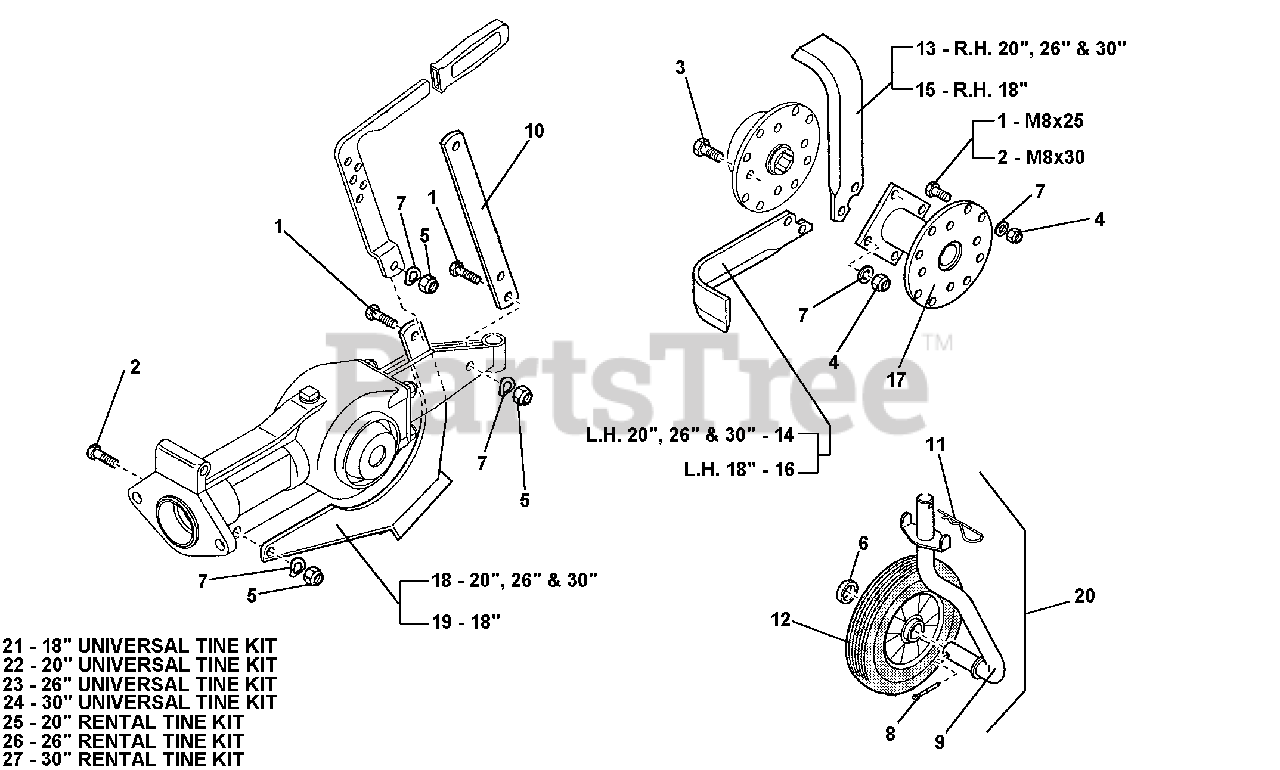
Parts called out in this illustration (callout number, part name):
1	SCREW, M8X25
2	SCREW, M8X30
3	SCREW, M8X35
4	NUT, SELF LOCKING, M8
5	NUT, SELF LOCKING, M8
7	WASHER, LOCK, M8.4
9	WHEEL SUPPORT PIN
12	RUBBER WHEEL
13	TINE, R.H., 20" - 30" TILLER
14	TINE, L.H., 20" - 30" TILLER
15	TINE, R.H., 18" TILLER
16	TINE, L.H., 18" TILLER
17	SPACER KNIVES
18	CERNTAL KNIFE
19	CENTRAL KNIFE
20	TRANSPORT WHEEL ASSEMBLY
21	18" UNIVERSAL TINE KIT
22	20" UNIVERSAL TINE KIT
23	26" UNIVERSAL TINE KIT
24	30" UNIVERSAL TINE KIT
25	20" RENTAL TINE KIT
26	26" RENTAL TINE KIT
27	30" RENTAL TINE KIT
